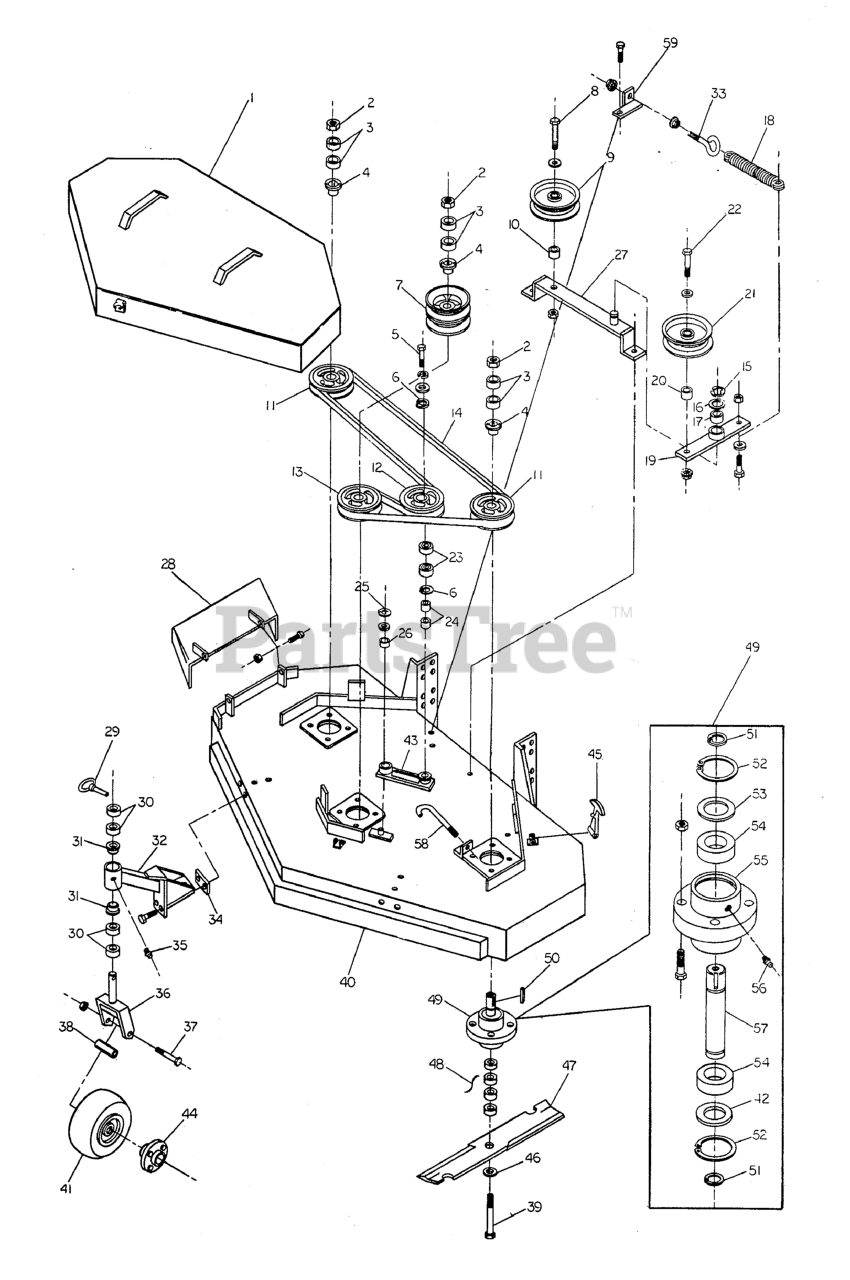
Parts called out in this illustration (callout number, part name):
1	48" DECK GUARD
2	NUT, 5/8-11 Hex
3	SPACER, .63 x 1.06 x .23
4	BUSHING, Tapered Hub
5	BOLT, 1/2-20 X 2-1/4 GD5 CZ
6	SNAP RING, Internal
8	BOLT, 1/2-13 X 3-1/2, HEX HD, GD5, CZ (SV)
9	PULLEY, Backside Idler
10	SPACER, .50 x 1.00 X .69
11	PULLEY, Spindle
12	PULLEY, Idler
13	SPINDLE PULLEY
14	BELT, Blade Spindle
15	C-CLIP
16	SHIM
17	BUSHING, Brass
18	SPRING, Extension
19	IDLER ARM, Complete
20	SPACER, .50 x 1.00 X .69
21	PULLEY, V-Idler
22	BOLT, 1/2-13 X 3" GD5 CZ
23	BEARING, BALL 11/16X1-9/16X15/32
24	INSERT, Bearing
25	C-CLIP
26	BUSHING, Brass
27	Idler Mount
28	CHUTE, DISCHARGE WELDMENT
29	PIN, Lynch
30	SPACER, 1.02 x 1.56 x .50
31	BUSHING, Flange
32	Caster Support
33	EYEBOLT
34	Caster Mount Spacer
35	GREASE FITTING
36	YOKE, Caster
37	BOLT, 1/2-13 x 5-1/2
38	AXLE, Caster Wheel
39	BOLT, 5/8-11 x 9-1/2
40	48" MOWER HOUSING
41	WHEEL & TIRE ASSEMBLY, White, 9 x 3.5 x 4, Complete
41	TIRE, Front, 9 x 3.5 x 4
41	HUB & BEARING ASSEMBLY, Complete, White
42	SPINDLE WASHER, Bottom
43	IDLER ARM
44	4 BOLT HUB W/ BEARING
45	RUBBER LATCH
46	WASHER, 5/8" USS
47	MOWER BLADE, 16-1/4"
48	SPACER, .63 x 1.06 x .23
49	SPINDLE ASSEMBLY, Complete
50	KEY, 1/4 SQ. X 2-1/2
51	SNAP RING, External
52	SNAP RING, Internal
53	SPINDLE WASHER, Top
54	BEARING
55	SPINDLE HOUSING
56	GREASE FITTING
57	SPINDLE SHAFT
59	Spring Anchor
